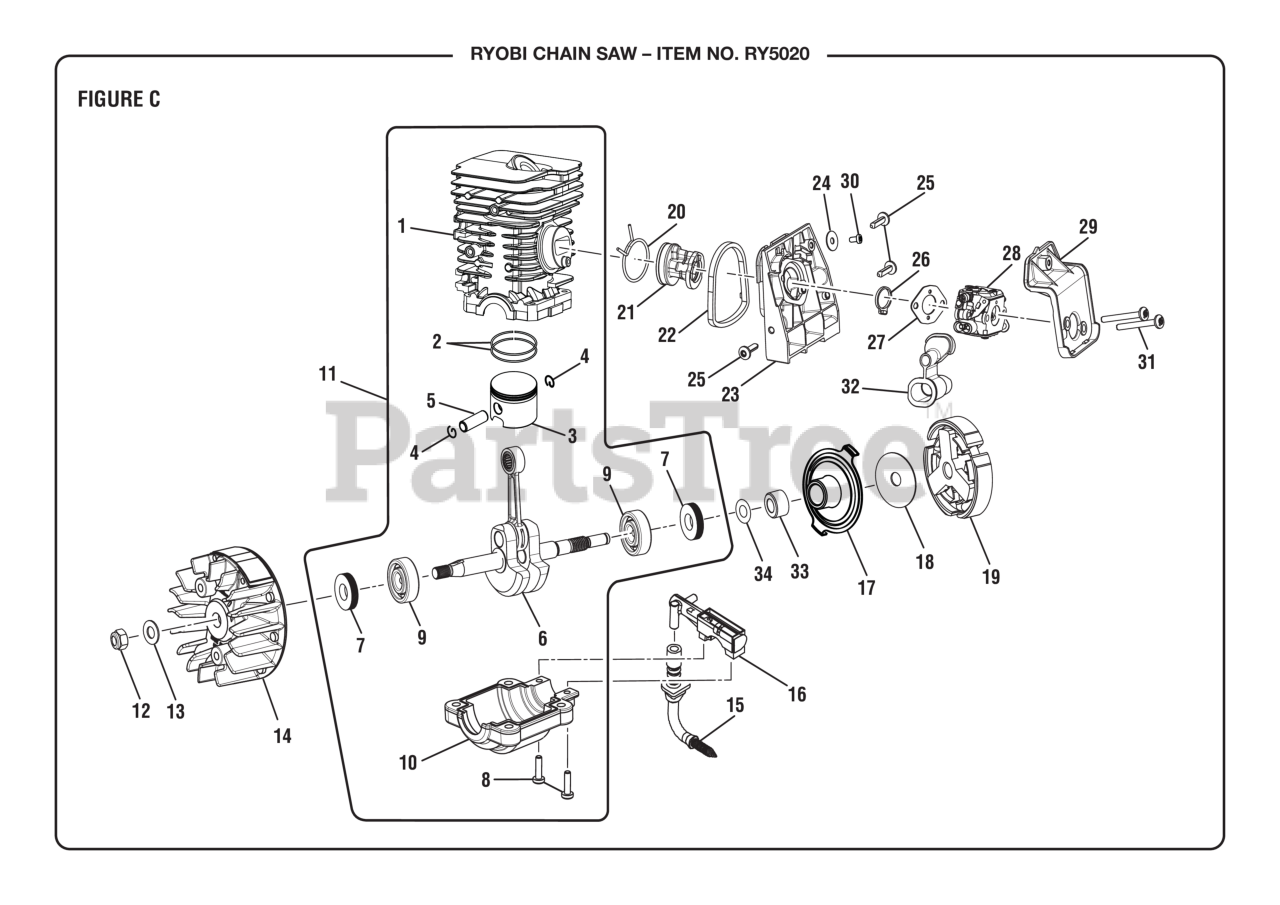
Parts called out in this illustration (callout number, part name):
2	Piston Ring
4	Spring Retainer
5	Piston Pin
6	Crankshaft Assembly
7	Shaft Seal
8	SCREW, (8/32 X 5/8 in. PAN HD TORX)
9	Ball Bearing
10	Crankcase
11	Short Block Assembly
12	Lock Nut (M8)
13	Washer (ID9 x OD17.7 x 1.1t)
14	Flywheel Assembly
15	OIL INTAKE TUBE W/FILTER
16	Oil Pump Assembly
17	Oil Pump Driver
18	Thrust Washer
19	Clutch Assembly
20	Wire Clamp
21	INTAKE BOOT
22	Carburetor Adaptor Seal
23	Carburetor Adapter
24	Flat Washer
25	Screws (10-14 x 3/4 in., T25 Torx Pan Hd. T.F.)
26	PLATE, CARBURETOR
27	Carburetor Gasket
28	Carburetor Assembly
29	AIR FILTER BASE
30	Screw (#8-16 x 5/16 in., T25 Torx Pan Hd. T.F.)
31	Screw (10-32 x 1 3/4 in.)
33	Bearing (Oil Pump Driver)
34	Washer (Oil Pump Drive Gear)
